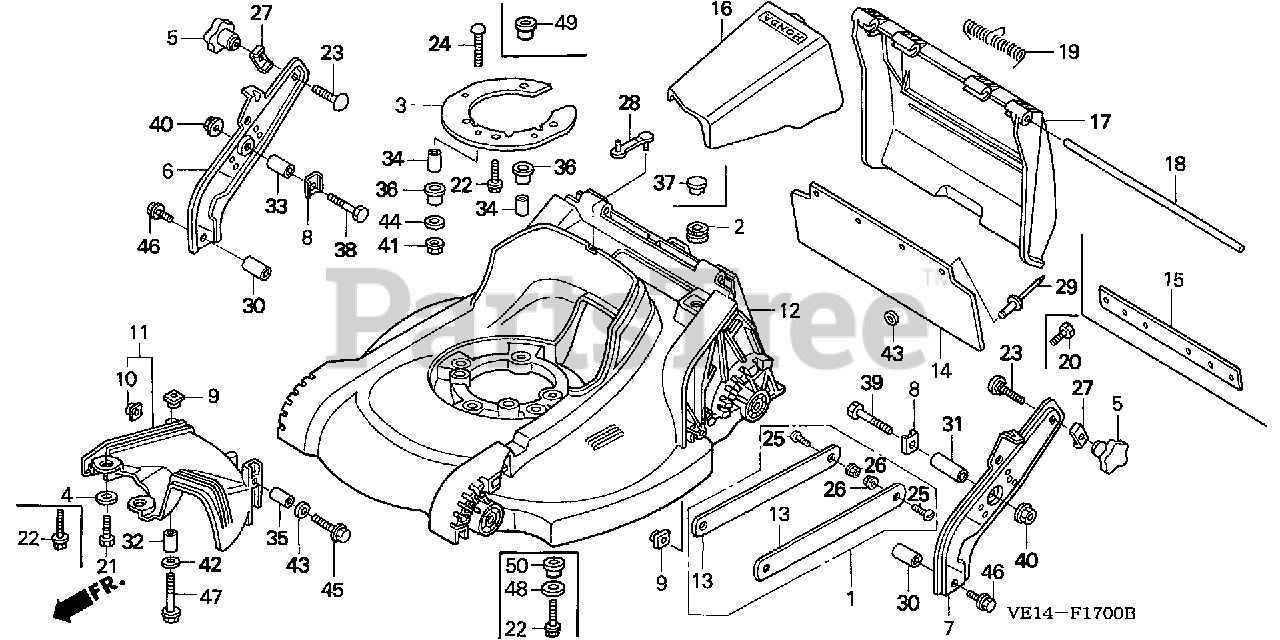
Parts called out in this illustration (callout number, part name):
1	GUARD KIT, HOUSING
2	RUBBER, BATTERY BOX MOUNTING
3	BED, ENGINE
4	PLATE, HANDLE SETTING
5	GRIP, HANDLE JOINT (UPPER)
6	STAY *NH246* (LOOSY GRAY)
7	STAY *NH246* (LOOSY GRAY)
8	HOLDER, HANDLE STAY
9	NUT, HEADLIGHT SETTING
10	NUT, SPECIAL (6X7)
11	GUIDE ASSY. *NH246* (LOOSY GRAY)
11	GUIDE ASSY., SCROLL *NH246* (LOOSY GRAY)
12	HOUSING, CUTTER *NH246* (LOOSY GRAY)
13	GUARD, HOUSING (N/A: USE P/N 06761-VE2-000)
14	SHIELD, RR.
15	PLATE, RR. SHIELD
16	STUFFING *NH105* (MAT BLACK)
17	GUARD, DISCHARGE
18	SHAFT, DISCHARGE GUARD
19	SPRING, GUARD RETURN
20	BOLT, ADJUSTING
21	BOLT, ENGINE SETTING
22	BOLT, ENGINE SETTING
23	BOLT, PAN (8X35)
24	BOLT, PAN (8X50)
25	SCREW, HOUSING GUARD (N/A: USE P/N 06761-VE2-000)
26	NUT, FLANGE (N/A: USE P/N 06761-VE2-000)
27	WASHER, FRAME JOINT
28	STRAP, CABLE
30	COLLAR, STAY (LOWER)
31	COLLAR, L. STAY (UPPER)
32	COLLAR, HANDLE
33	COLLAR, R. STAY (UPPER)
34	COLLAR, ENGINE BED
35	COLLAR, SCROLL
36	COLLAR, INSULATING
38	BOLT, HEX. (8X40)
39	BOLT, HEX. (8X55)
40	NUT, FLANGE (8MM)
41	NUT, FLANGE (8MM)
42	WASHER, PLAIN (8MM)
43	WASHER, PLAIN (6MM)
44	WASHER, PLAIN (8MM)
45	BOLT, FLANGE (6X35)
46	BOLT, FLANGE (8X22)
47	BOLT, FLANGE (8X45)
